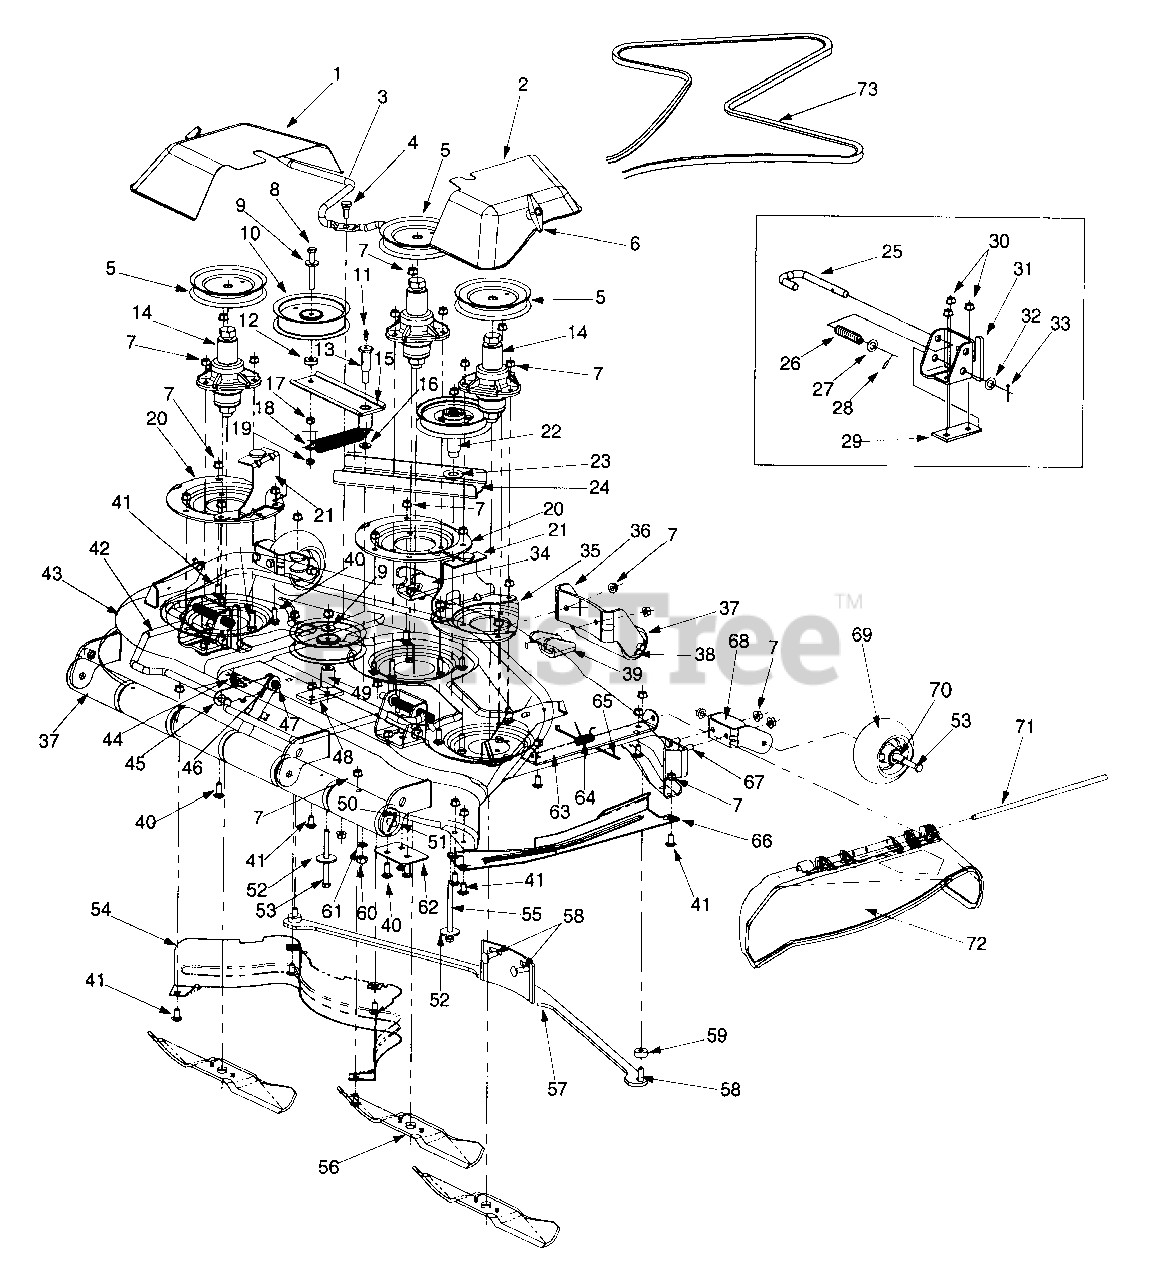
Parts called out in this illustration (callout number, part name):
4	Shoulder Screw 3/8-16
5	Pulley
6	Wingnut Knob
7	Flange Lock Nut 3/8-16
8	Hex Cap Screw 3/8-16 x 3.0
9	Flat Washer .385 ID x 1.0 OD
10	Idler Pulley 5.0
11	Grease Fitting
13	Shoulder Bolt
14	Deck Spindle Ass'y
17	Lock Nut 3/8-16
18	Extension Spring 1.0 OD x 5.78 Lg
19	Jam Nut 3/8-16
23	Flat Washer .78 ID x 1.59 OD
26	Compression Spring
27	Flat Washer .536 ID x .93 OD
28	Spirol Spring Pin
33	Cotter Pin
37	Front Roller
38	Roller Pin
41	Carriage Bolt 3/8-16 x .75
42	Deck Support Rod
47	Shoulder Screw
50	Cotter Pin
51	Pin Roller
52	Flat Washer
53	Hex Cap Screw 3/8-16 x 4.25
55	Hex Cap Screw 3/8-16 x 4.5
56	Blade
59	Spacer .406 ID x 1.0 OD
60	Hex Nut 7/16-14
61	Lock Washer 7/16
64	Torsion Spring
65	Cable Tie
67	Hex Cap Screw 3/8-16 x .880
71	Hinge Pin
72	Deflector Chute
73	V-Belt Z-54
